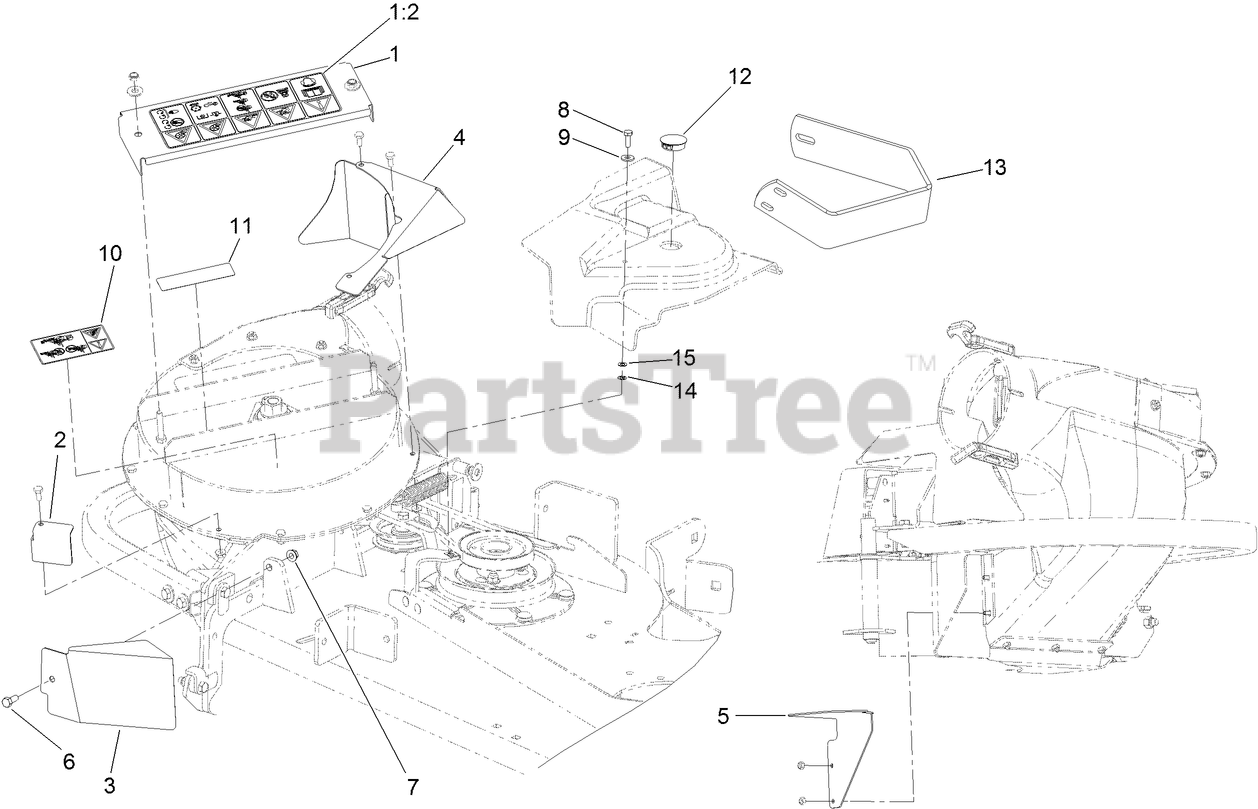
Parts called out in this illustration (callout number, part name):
1	COVER-BEARING
1:2	DECAL-DANGER
2	GUARD-LEFT
3	GUARD-FRONT
4	GUARD-TOP
5	GUARD-LOWER
6	SCREW-HH
7	NUT-HF
8	SCREW-HH
9	WASHER-FLAT
10	DECAL-WARNING
11	DECAL-MISSING, COVER
12	PLUG-PLASTIC
13	GUARD-MUFFLER
14	NUT-RETAINER
15	WASHER-FLAT
